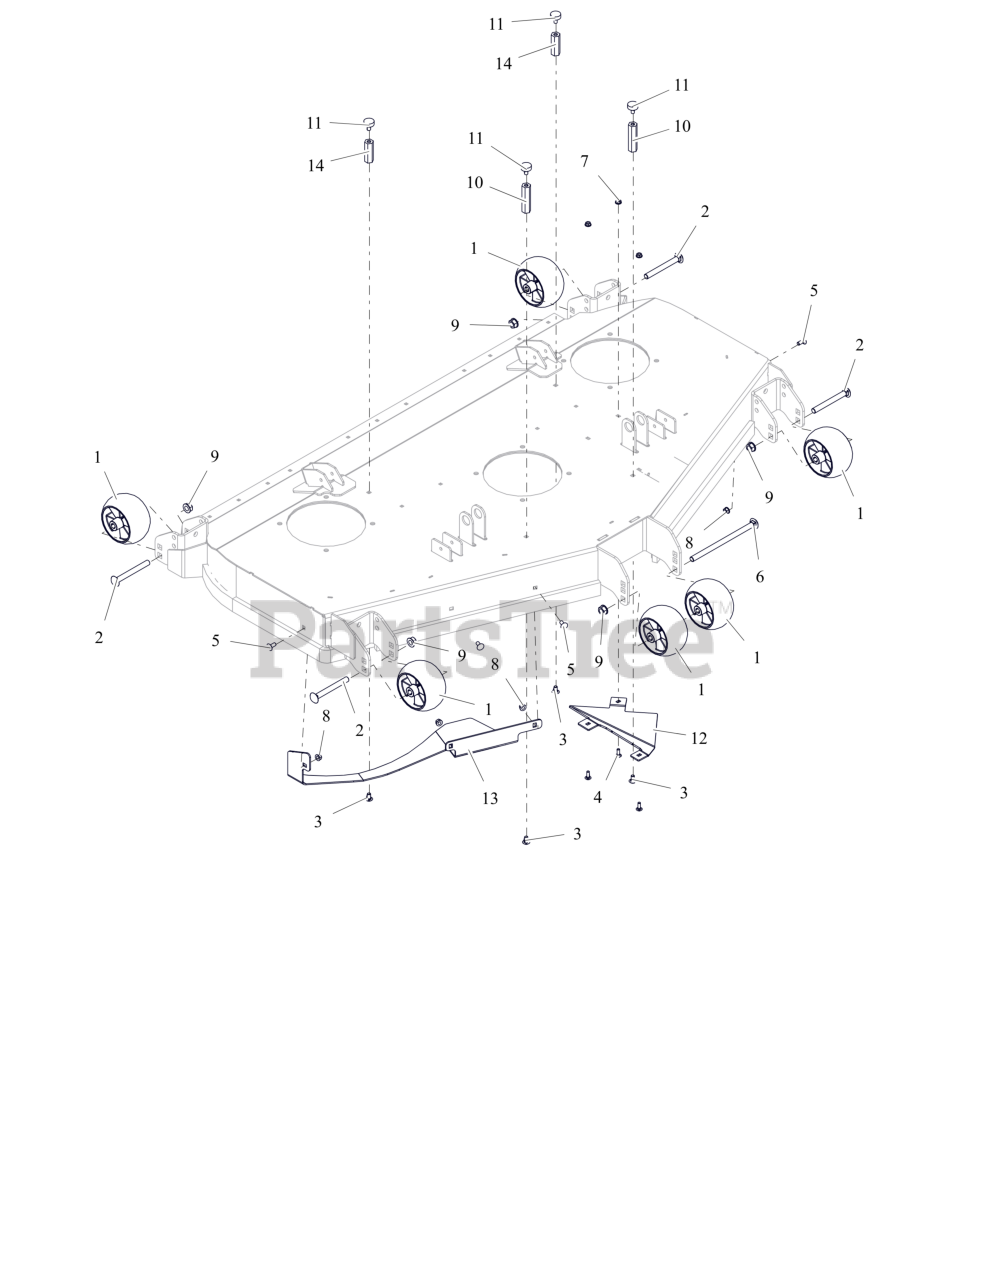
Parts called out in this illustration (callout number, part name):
1	WHEEL, ANTI SCALP - 5X3 CTR W/RIBS
2	BLT,RHSN .50-13X4.50 G5 ZCC
3	BLT,RHSSN.31-18X.625 G5 ZCCP30
4	BLT, RHSN .25-20X.750 G5 ZCC
5	BLT, RHSSN.31-18X.750 G5 ZCC
6	BTL,RHSN .500-13 X 8.5S G5 ZCC
7	NUT-LK-CTR-FLG .25-20 ZC120
8	NUT,LK-CTR-FLG .31-18 GF ZCC
9	NUT-LK-CTR-FLG .500-13 GG ZCC
10	NUT, COUPLING .31-18 X 3.00
11	BUMPER, RUBBER
12	BAFFLE, INSERT TRIANGLULAR (ORANGE)
13	DEFLECTOR, BAFFLE BOLT-IN (ORANGE)
14	NUT, .31-18 X 2.25 LG COUPLING
